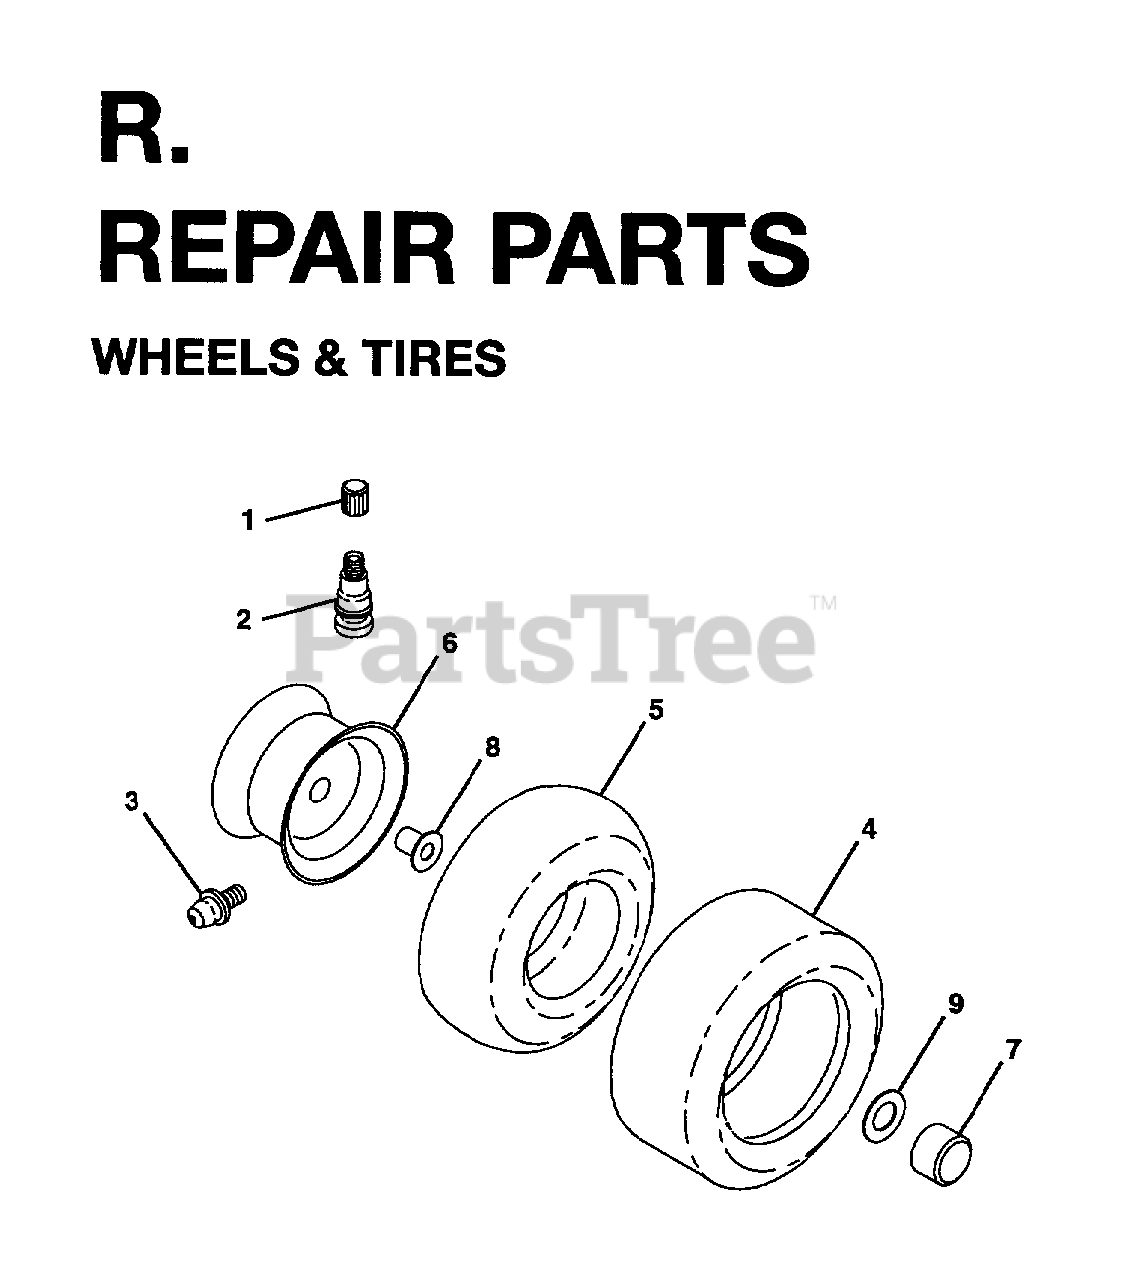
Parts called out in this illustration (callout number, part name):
1	VALVE CAP
2	VALVE STEM LT
3	FITTING LT
4	TIRE
4	REAR TIRE
5	TUBE.5.3/4.5/6
5	TUBE.16X6.5/7.5-8
6	RIM
6	RIM REAR 8"
7	CAP-HUB FRONT LT
8	BEARING T
